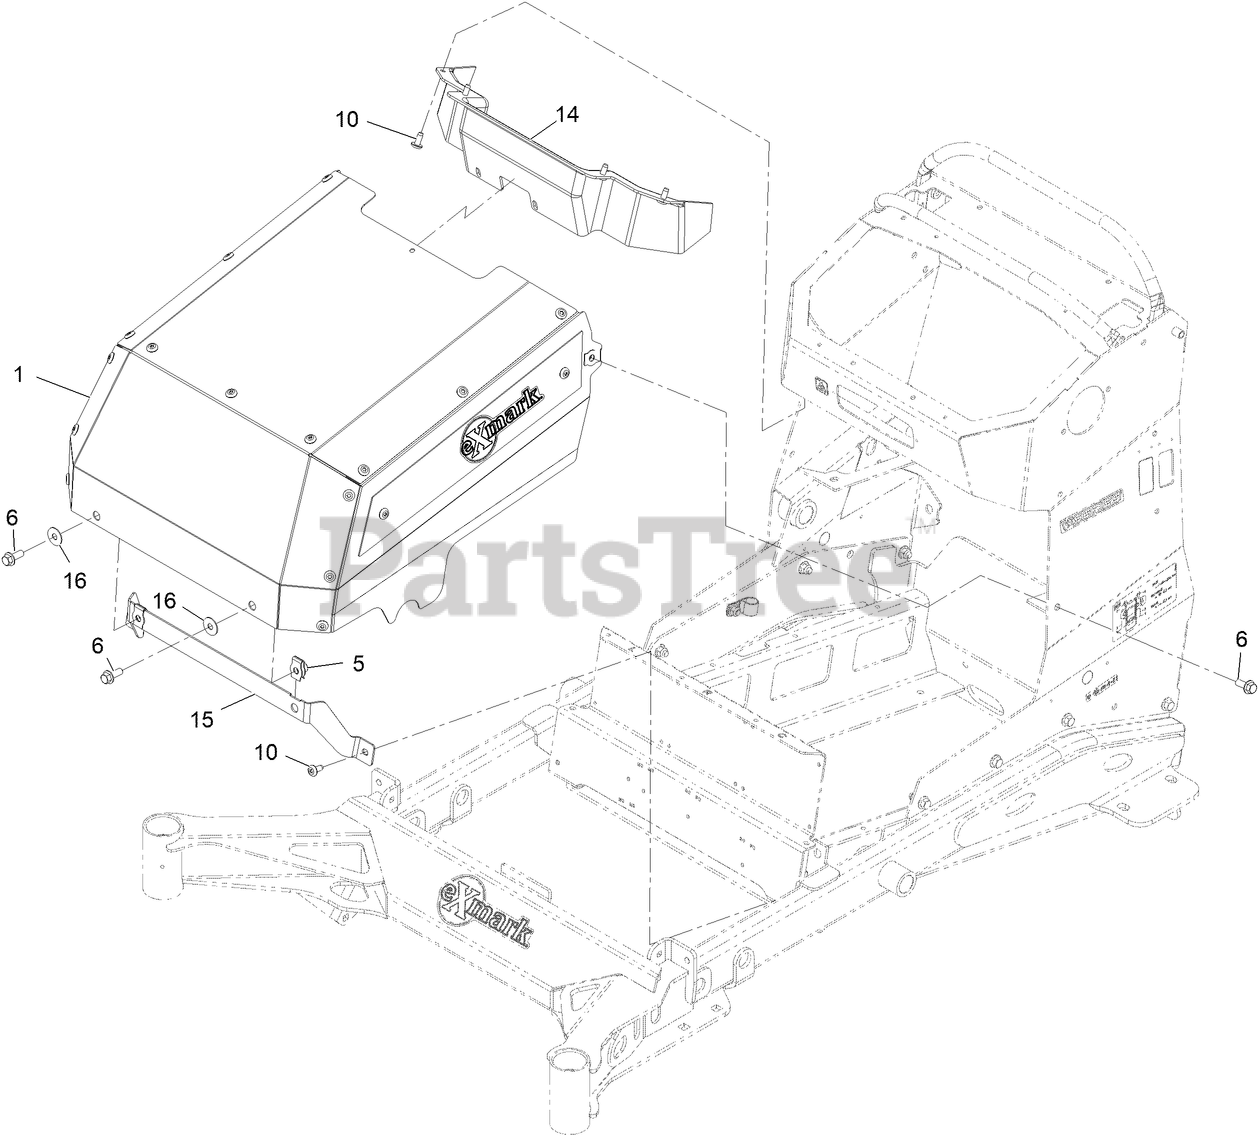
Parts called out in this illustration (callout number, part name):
1	ASM-BATTERY COVER
5	NUT-TINNERMAN
6	SCREW-HHF 3/8-16 X 1
14	COVER-HOOD
15	BRACKET-MOUNT, COVER
